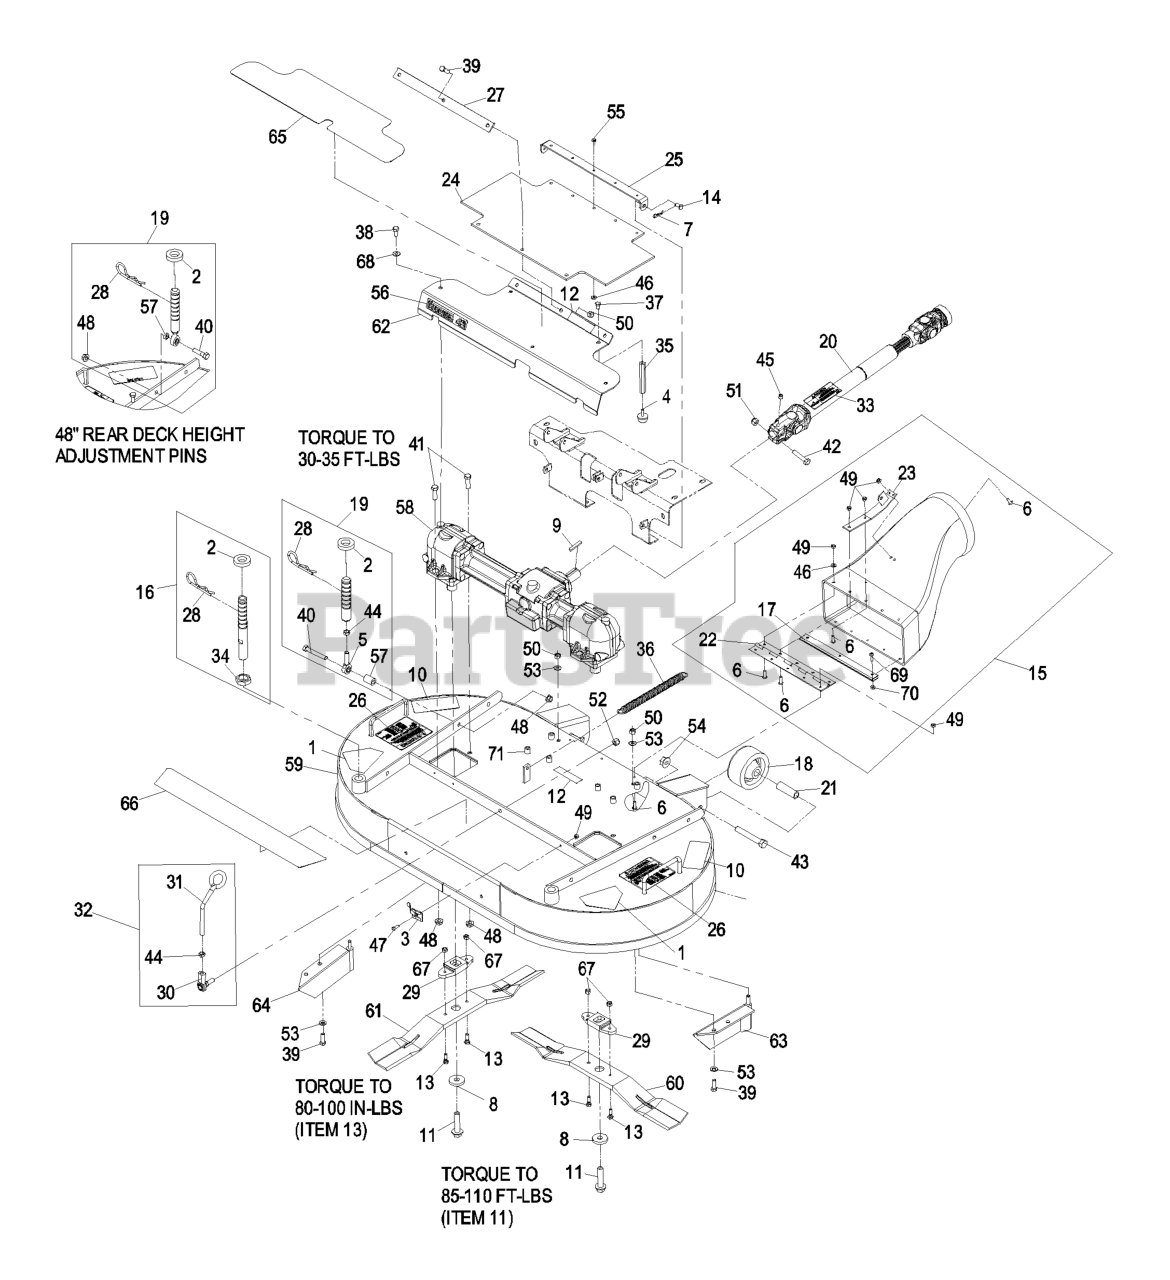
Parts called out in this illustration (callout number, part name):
1	DECAL-DANGER
2	SPACER-DECK SUPPORT
3	CLIP-DECK, HOLD UP ROD
4	BUMPER-RUBBER
5	BALLJOINT
6	SCREW-HEAD, TRUSS
7	PIN-COTTER
9	KEY-SQUARE
10	DECAL-TORQUE
11	BOLT-BLADE
12	DECAL-COVER, MISSING
13	BOLT-SHEAR
14	PIN-CLEVIS
15	DISCHARGE TUBE ASM
16	FRONT DECK HEIGHT ADJUST
17	GUARD-PLENUM
18	ROLLER-DECK
19	REAR DECK HEIGHT ADJUST A
20	DRIVE SHAFT ASM
21	SPACER-ROLLER
22	HINGE-PIANO
23	MOUNT-SPRING
24	GUARD-PTO
25	BRACKET-GUARD, PTO
27	STRAP-DRIVE, LINE COVER
28	PIN-CUT HEIGHT
29	DRIVER-BLADE
30	BALLJOINT-RH
31	LATCH-DECK
32	DECK LATCH ASM
33	DECAL-DRIVELINE
34	NUT-JAM
35	STAND-OFF
36	SPRING-EXTENSION
37	SCREW-HH
38	SCREW-HH
39	SCREW-HH
40	SCREW-HH
41	SCREW-HH
42	SCREW-HH
43	SCREW-HH
44	NUT-HEX
45	SCREW-SET, HSH
46	WASHER-FLAT
48	NUT-HHF, WHIZ
49	NUT-LOCK, NI
50	NUT-LOCK, NI
51	NUT-LOCK, NI
52	NUT-LOCK
53	WASHER-SPRING
54	NUT-HHF
55	RIVET-BLIND
56	DECAL,COMMERCIAL 42
57	TUBE-INTERLOCK
58	GEARBOX ASM
59	DECK ASM
60	BLADE,22 INCH LH
61	BLADE,22 INCH RH
62	ASM,GEARBOX COVER 42 W/DE
63	BAFFLE-LH
64	BAFFLE-RH
65	PAD-ANTI SKID
66	PAD-SKID, ANTI
67	NUT-LOCK, NI
68	WASHER-PLAIN
69	BOLT-CARR
70	NUT-LOCK, NI
71	NUT-CLINCH
